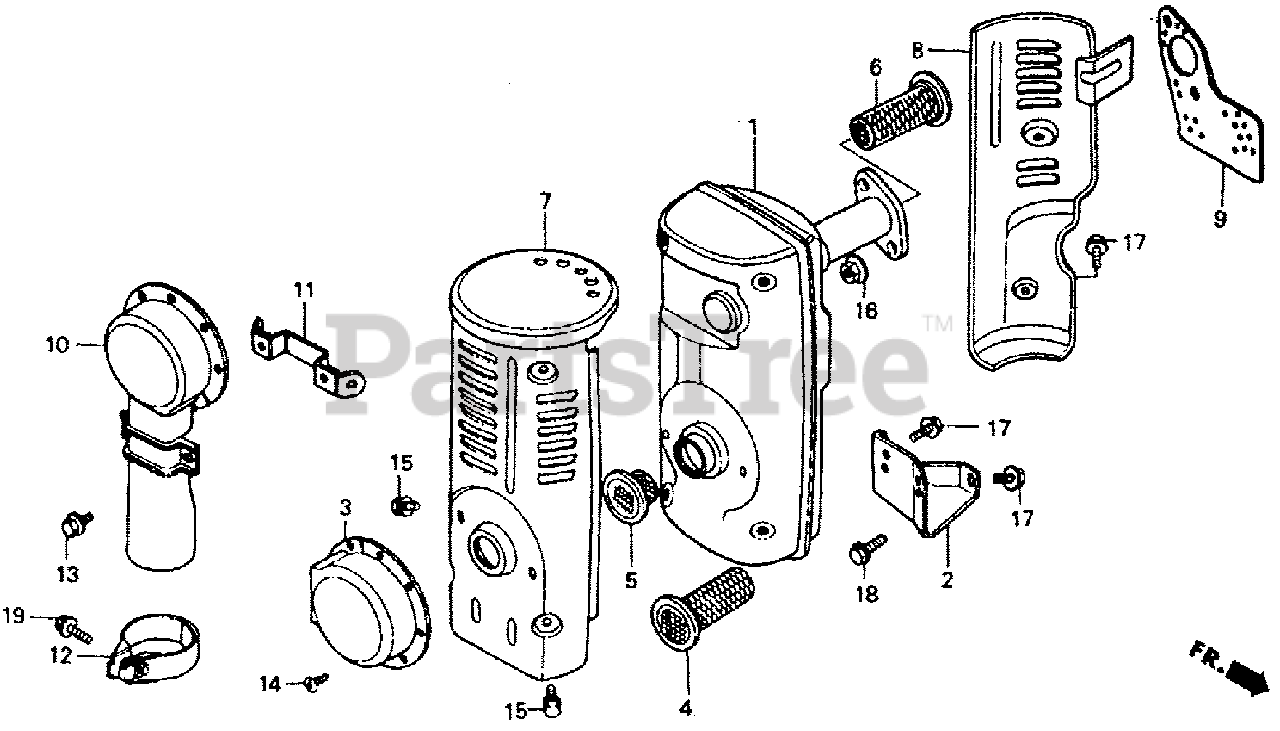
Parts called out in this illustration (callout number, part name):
1	MUFFLER
2	STAY, MUFFLER
3	DEFLECTOR, MUFFLER
4	ARRESTER, SPARK
5	FLANGE, BAFFLE
7	PROTECTOR A, MUFFLER
8	PROTECTOR B, MUFFLER
9	GASKET, MUFFLER
10	PIPE, MUFFLER
11	HOLDER, TAIL PIPE
12	BAND, TAIL PIPE
13	BOLT, FLANGE (6X8)
14	SCREW, TAPPING (4X8)
14	SCREW, TAPPING (4X6)
15	BOLT-WASHER (6X10)
16	NUT, FLANGE (8MM)
17	BOLT, FLANGE (6X10)
18	BOLT, FLANGE (8X16)
19	BOLT, FLANGE (8X16)
